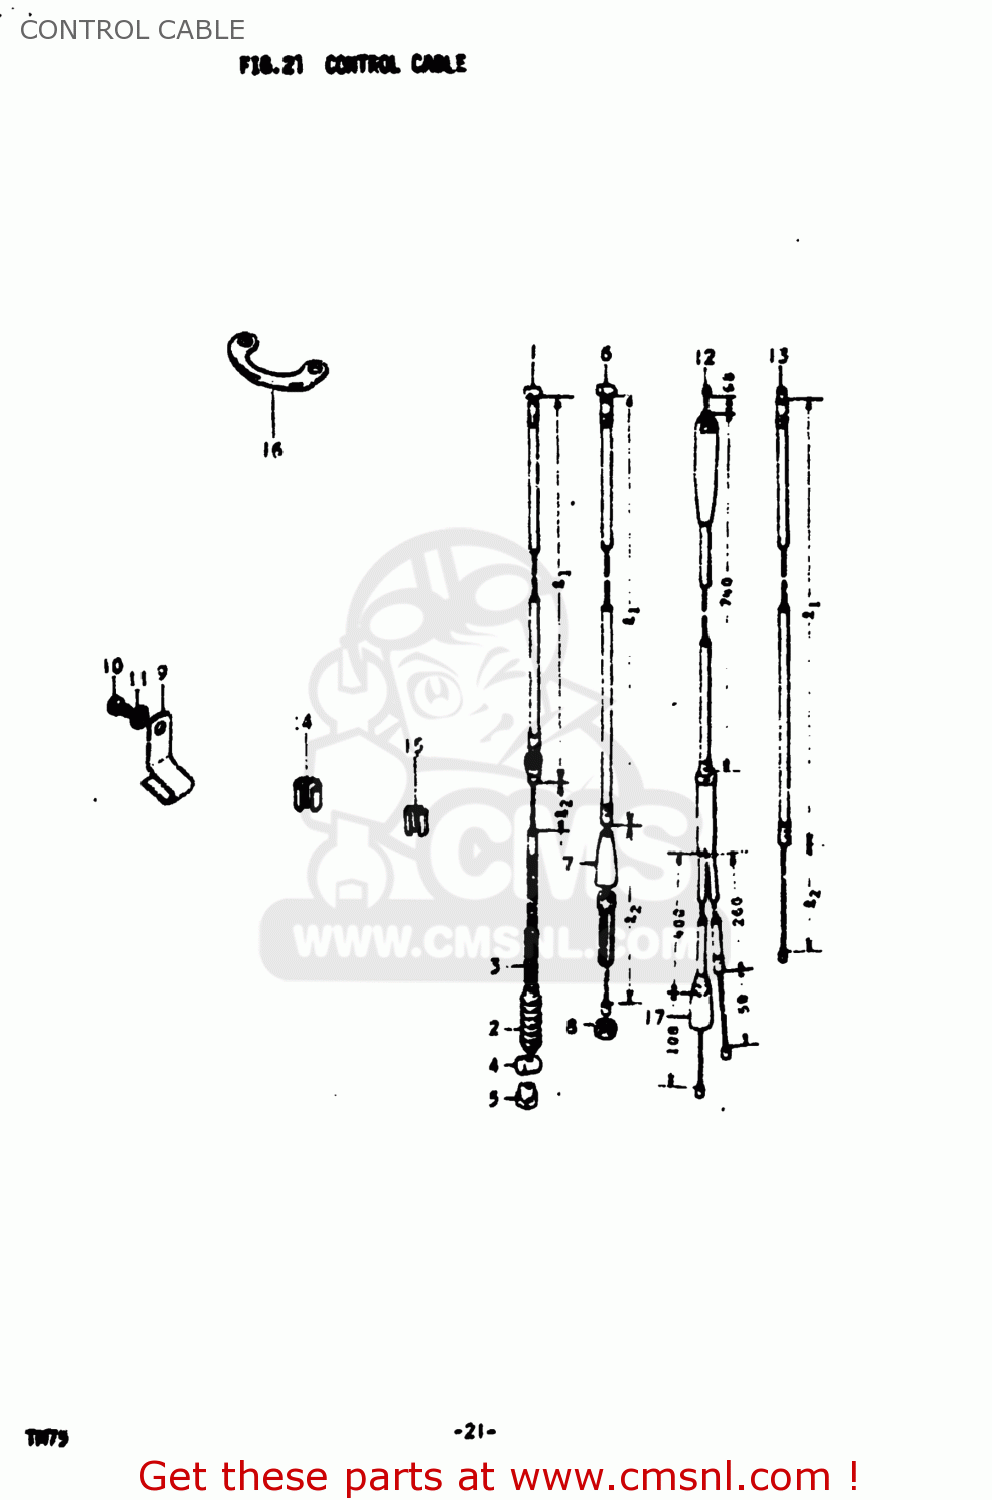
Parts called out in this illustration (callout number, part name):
1	CABLE ASSEMBLY,FRONT BRAKE
2	SEAL,DUST(7X16X75)
3	SPRING
4	PIN,10X19
5	NUT
6	CABLE ASSY,CLUTCH
7	SEAL,DUST(7X18X30)
8	NUT
9	CLAMP
10	BOLT
11	LOCK WASHER
12	CABLE ASSEMBLY,THROTTLE
13	CABLE COMP,STARTER
14	CLIP
15	CLIP
16	GUIDE,CABLE
17	SEAL,DUST(7X18X30)
